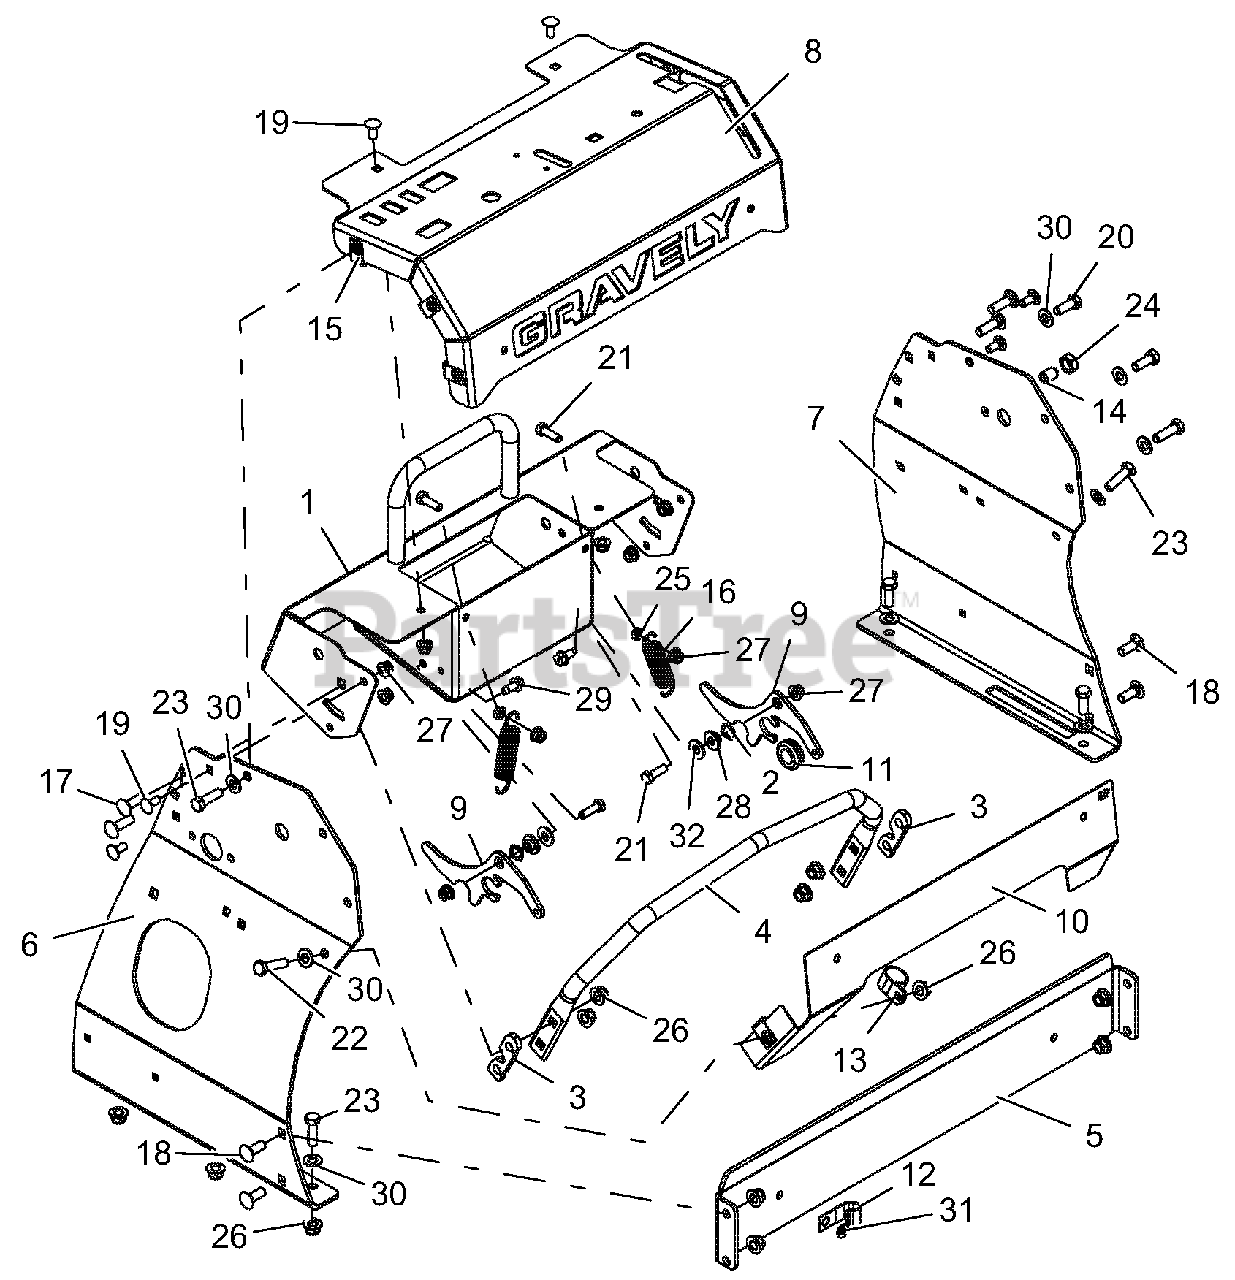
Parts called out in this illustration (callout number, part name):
1	WLDMT, CONTROL PANEL, PRO-STANCE
2	WAVE WASHER .531X.781X.125 FH
3	SHIM, BAR 5 DEG SPEED-BLACK
4	STOP, FORWARD STEERING
5	STIFFENER, TOWER
6	PANEL, TOWER RH, PRO-STANCE
7	PANEL, PROSTANCE LH TOWER
8	KIT, DASH WITH DECAL EFI
9	LATCH, PAD MOUNT
10	PLATE, FRONT BACKER-BLACK
11	GROMMET, SPLIT RUBBER
13	CLAMP, CUSHIONED STEEL REV
14	BALL SPRING PLUNGER, .500-13
15	NUT, RTNR .375-16X.37
16	SPRG, EXTENSION
17	BLT-RDHDSQNK .38-16X1.25 G5 YWZC
18	BLT-RDHDSQNK .38-16X1.00 G5 YWZC
19	BLT-RDHDSQNK .31-18X.75 G5 YWZC
20	BLT-HEX .38-16X1.00 GR5 YWZC
21	BLT-HEX .31-18X1.00 GR5 YWZC
22	BLT-HEX .38-16X1.50 GR5 YWZC
23	BLT-HEX .38-16X1.25 GR5 YWZC
24	NUT, JAM .500-13 YWZC
25	@NUT-LK-CTR-JAM .31-18 YWZC
26	NUT-LK-NYL-FLG .38-16 YWZC
27	NUT-LK-NYL-FLG .31-18 YWZC
28	BSHG, FLG .32X.500.344X.880
29	SCR-TAP .31-18X.75 HWH TR YWZ
30	WSHR-FL-STL.406X.812X.065 YWZ
31	WSHR-FL-STL.281X.62X.065 YWZC
32	WSHR-FL-STL.38X.875X.083 YWZC
